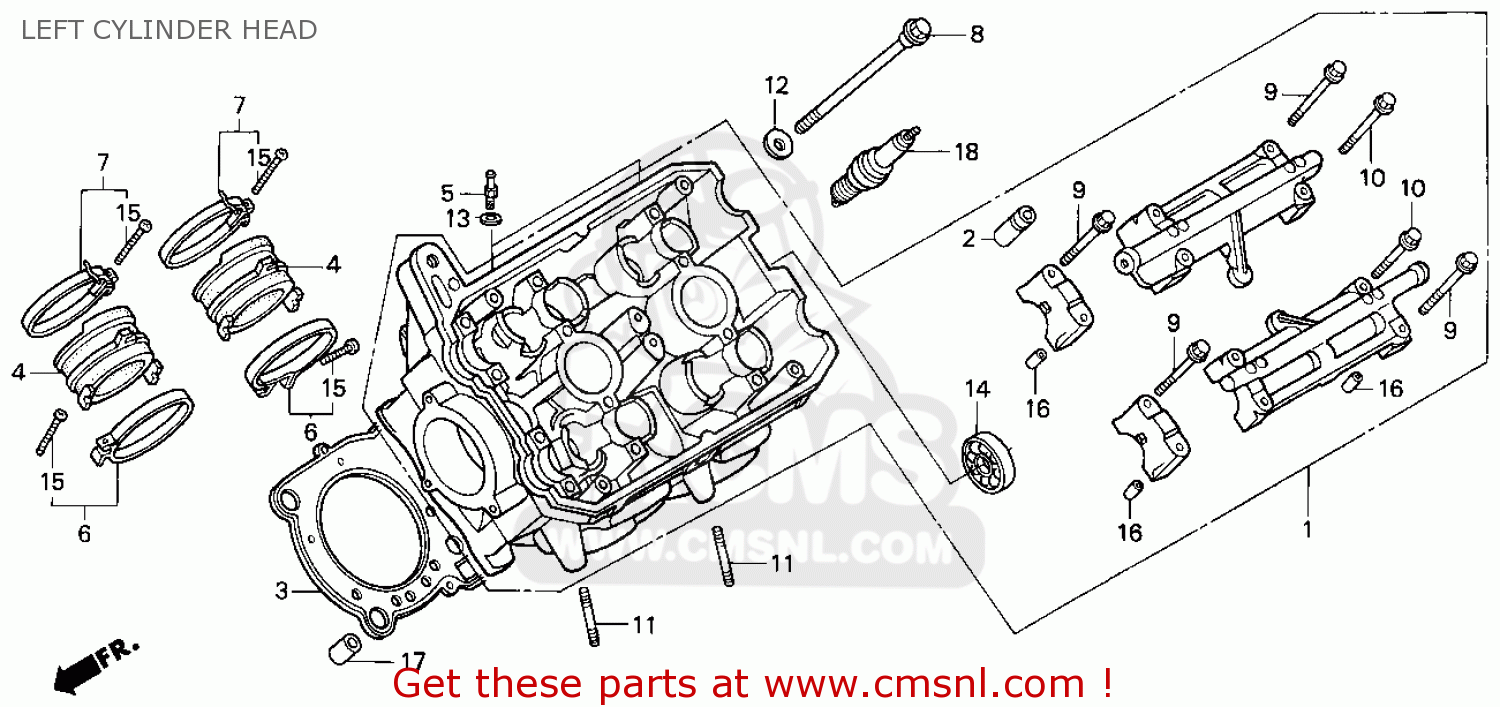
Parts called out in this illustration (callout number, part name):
1	HEAD ASSY.,L.CYLI
2	GUIDE,VALVE
3	GASKET,CYLN HEAD (NAS)
4	INSULATOR,CARB
5	JOINT,BOOST
6	BAND,INSULATOR
7	BAND,INSULATOR
8	BOLT,FLANGE,10X87
9	BOLT,FLG.,6X45.5
10	BOLT,FLG.,6X39.5
11	BOLT STUD 8X24
12	WASHER,10MM
13	WASHER 5MM
14	BRG,BALL RADIAL 6
15	SCREW,PAN 5X18
17	DOWEL,PIN,12X20
18	PLUG,SPARK(CR8EH9
